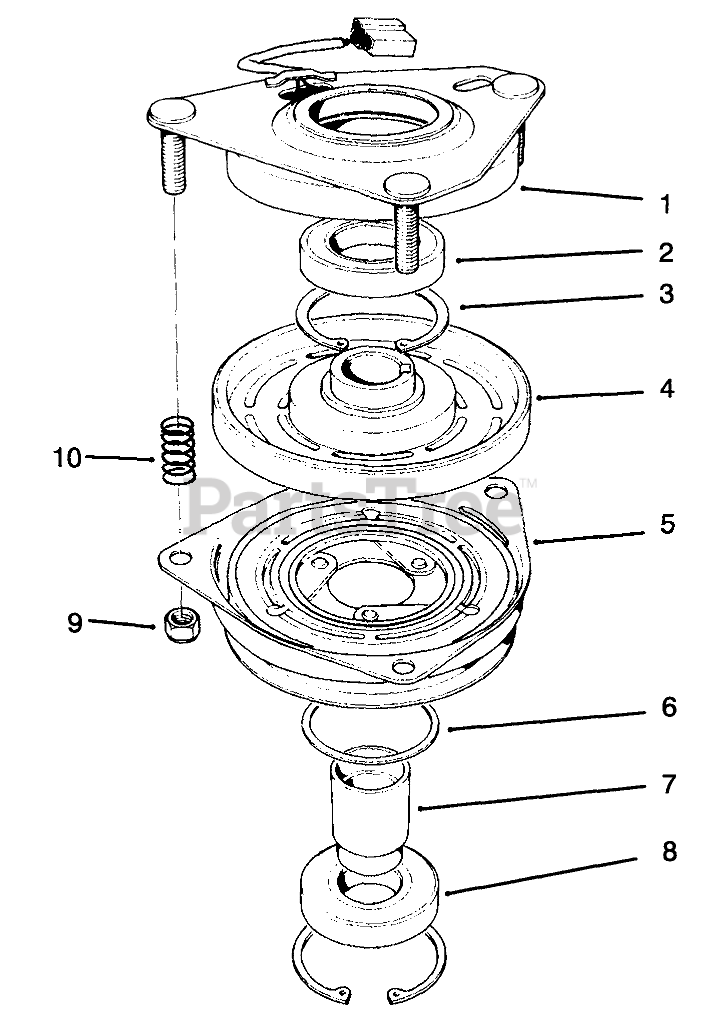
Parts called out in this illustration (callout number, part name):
1	Field Assembly (Incl. Ref. # 2 & 3)
2	BEARING-FIELD
3	RING-RETAINING
4	Field Coil, Rotor & Bearing Assembly (Incl. Ref. # 1)
5	Armature & Pulley Assembly (Incl. Ref. # 3, 6, 7, & 8)
6	SPACER-BEARING, PULLEY
7	COLLAR-BEARING
8	BEARING-PULLEY
9	NUT-HEX
10	SPRING
